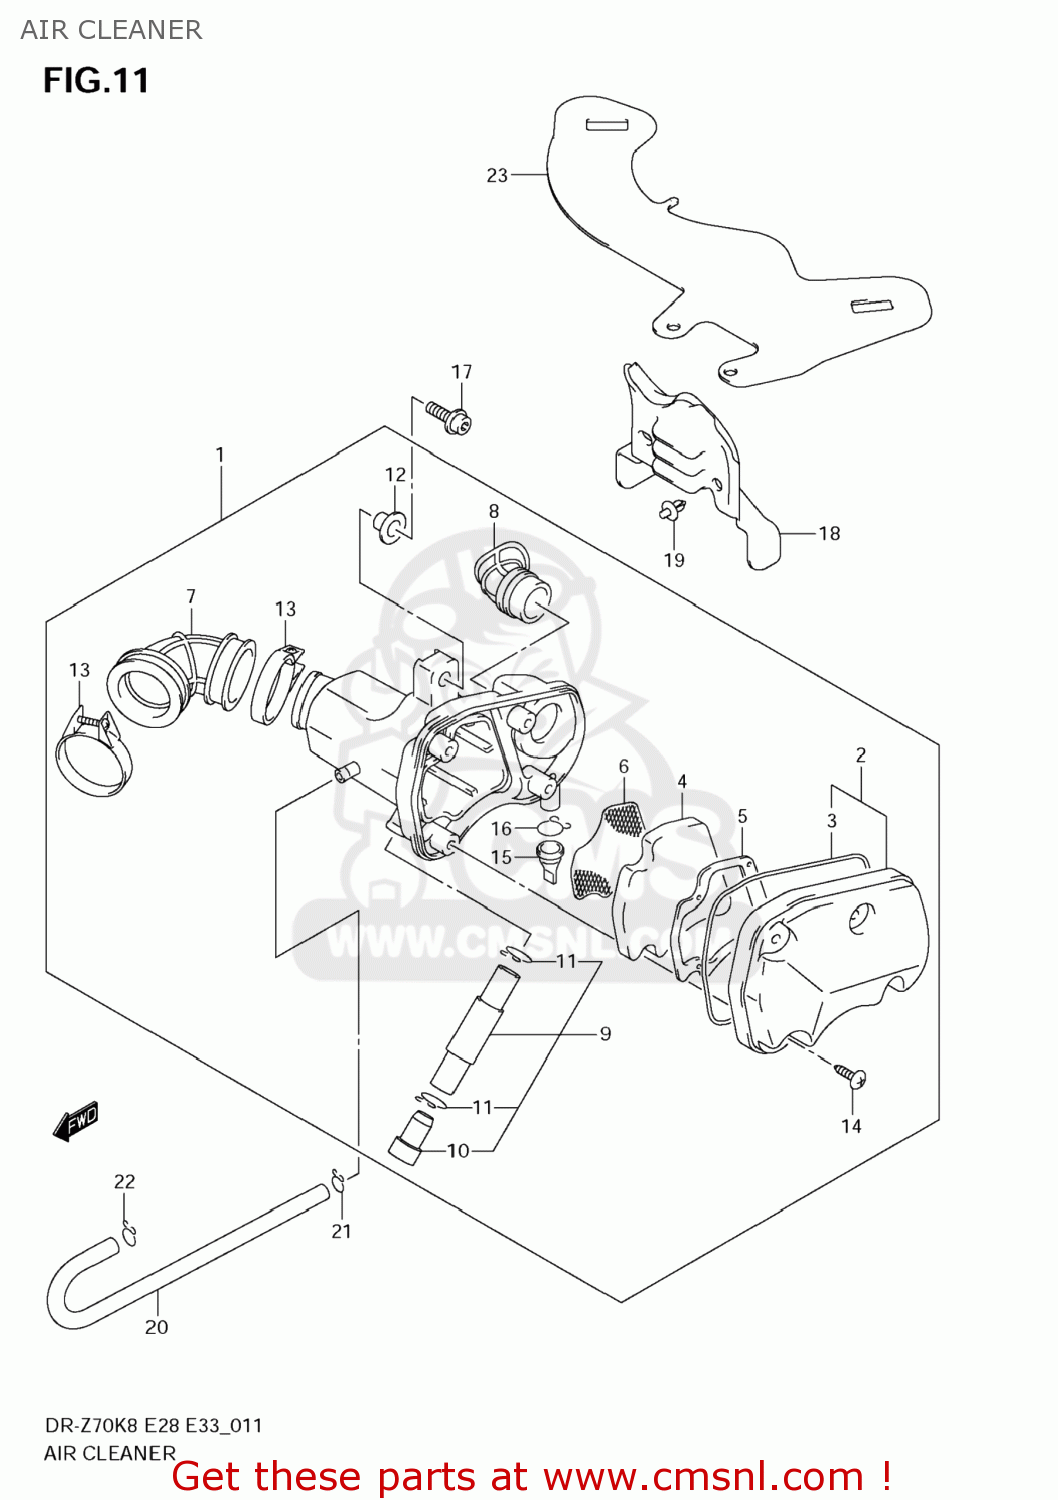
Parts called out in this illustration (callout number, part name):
1	CLEANER ASSY,AIR
2	CAP
3	GASKET (NAS)
4	FILTER
5	HOLDER
6	TRAP,FLAME
7	TUBE,OUTLET
8	TUBE,INLET
9	TUBE,DRAIN
10	PLUG
11	CLIP
12	SPACER(6.2X8.4X10.9)
13	CLAMP
14	SCREW
15	TUBE,DRAIN
16	CLIP
17	BOLT
18	COVER,CLEANER INLET
19	CLIP(BLACK)
20	HOSE,BREATHER
21	CLIP
22	CLIP
23	SHEET,AIR CLEANER INLET
